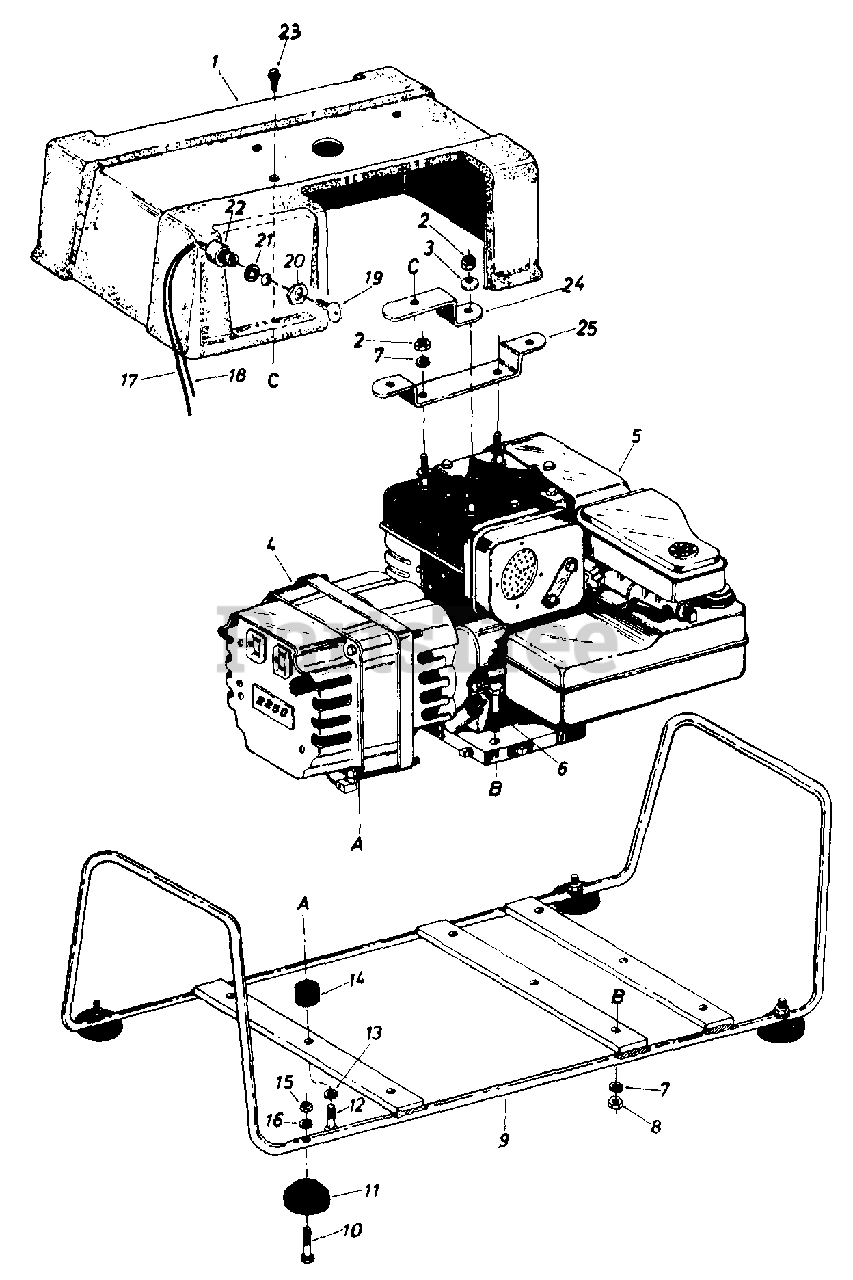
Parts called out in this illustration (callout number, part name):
1	Cover
2	Hex Nut 5/16-18 Thd.
3	Belleville Wash. .345 I.D. x .88 O.D.
4	Generator
5	Engine
6	Hex Bolt 5/16-18 x 1.75" Lg.
7	L.-Wash. 5/16" I.D.
8	Hex Nut 5/16-18 Thd.
9	Carriage Ass'y.
10	Truss Mach. Scr. 1/4-20 x 1.75" Lg.
11	Rubber Bumper
12	Hex Sems Bolt 5/16-18 x .62" Lg.
13	L.-Wash. 5/16" I.D.
14	Rubber Bumper
15	Hex Nut 1/4-20 Thd.
16	L.-Wash. 1/4" I.D.
17	Electric Wire
18	Electric Wire
19	Ignition Key
22	Ignition - Safety Switch
23	Hex Wash Hd. TT-Tapp Scr. 5/16-18 x .50" Lg.
24	Cover Bracket
25	Cover Bracket
